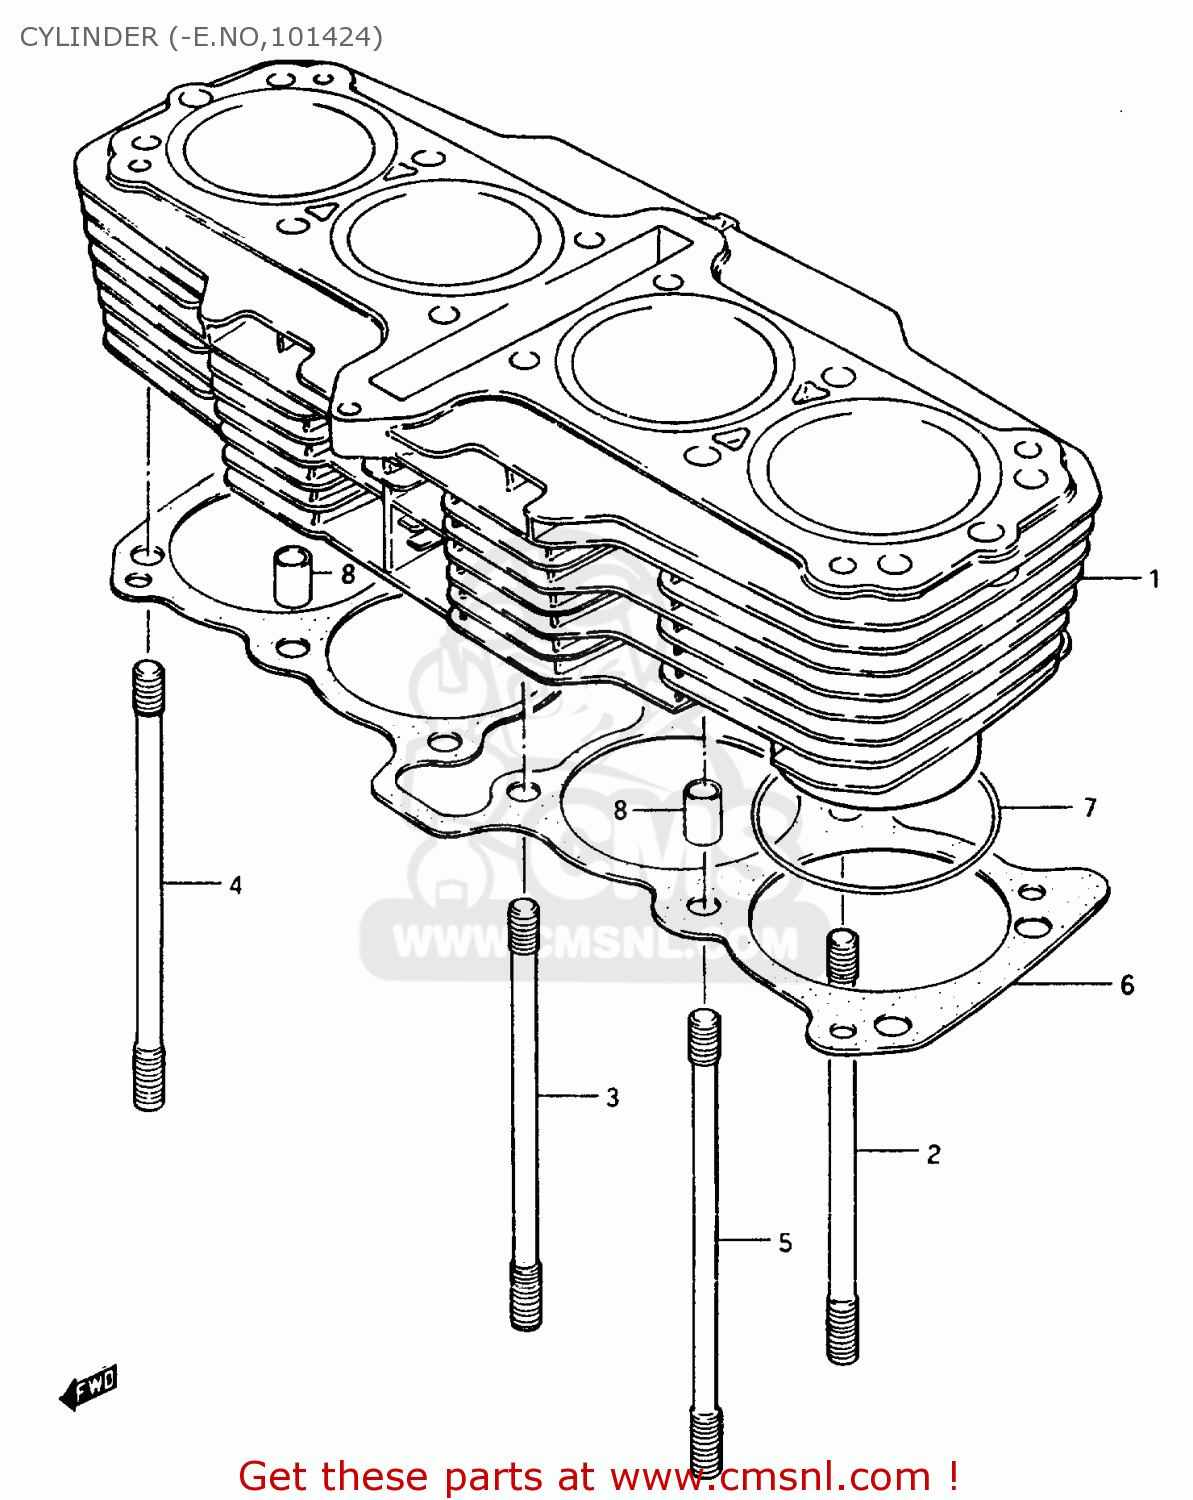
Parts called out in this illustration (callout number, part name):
1	CYLINDER
2	BOLT,STUD
3	STUD
4	STUD
5	BOLT,STUD
6	GASKET,CYLINDER HEAD (NAS)
7	O RING(D:2,ID:77)
8	PIN
